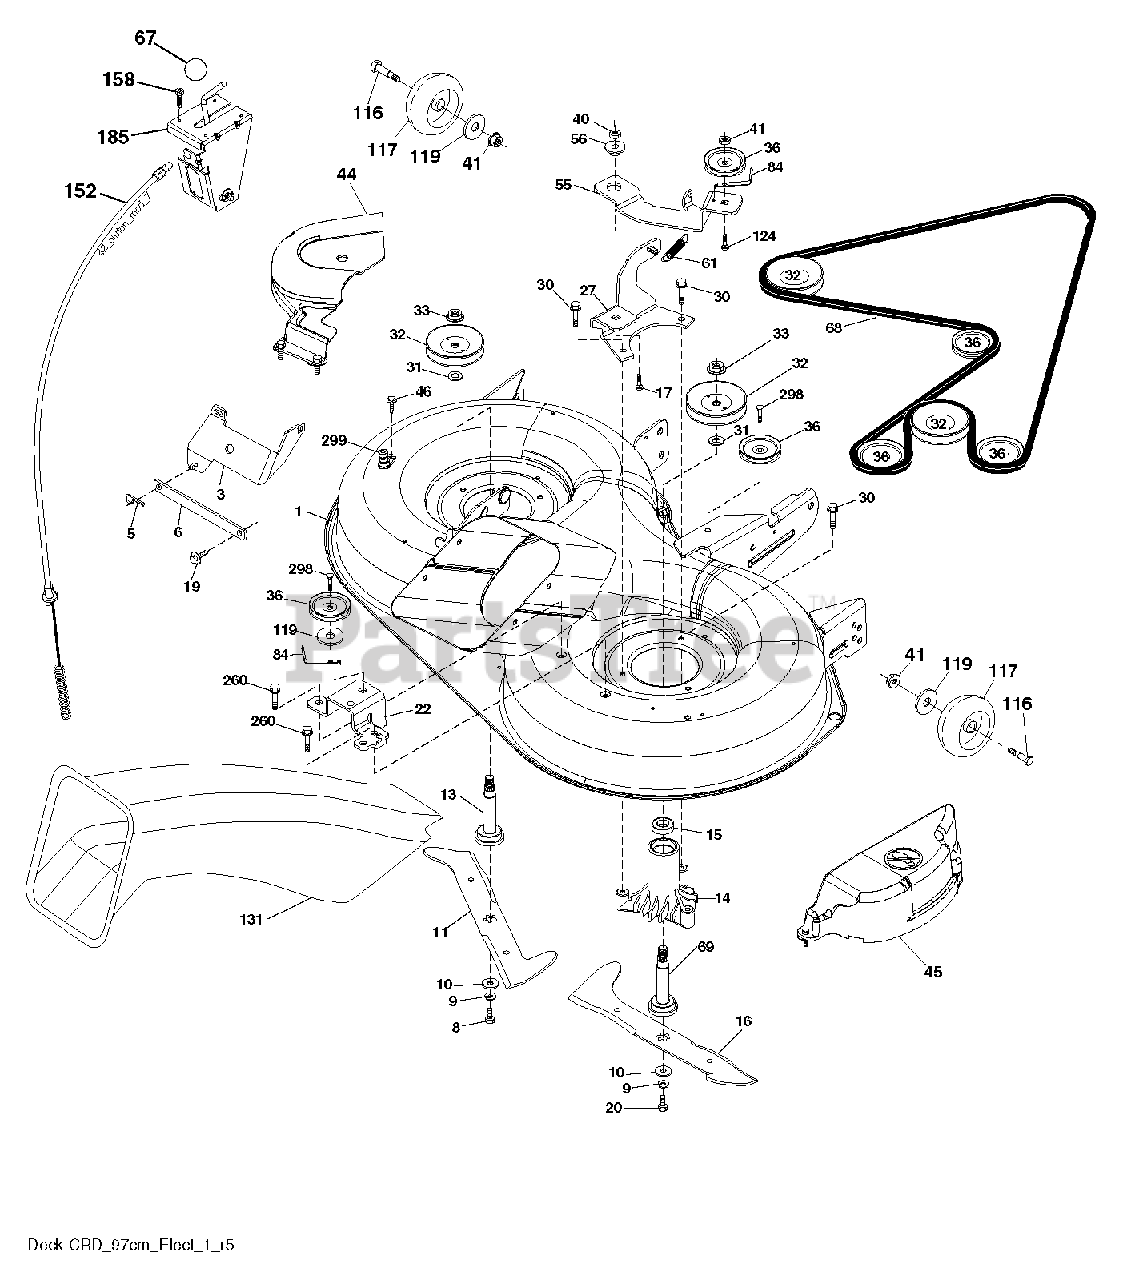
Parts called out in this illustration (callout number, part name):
3	BRACKET.ASM.BAR.SWAY.CHASS
5	RETAINER-SPRNG RB
6	BAR SWAY
9	LOCKWASHER
10	WASHER.BLADE
11	BLADE.3N1.LH.CRD.97
13	SHAFT ASM VENT
14	HSG MANDREL
16	BLADE.3N1.RH.CRD.97
17	BOLT.3/8-14X1.25
19	BOLT SHD 5/16-18
22	BRACKET.SUPT.IDLER.REAR.RH
27	BRACKET.ASM.SUSP.REAR.RH.
30	SCREW, WASHER HEAD
31	WASHER.SPACER.MANDREL
32	PULLEY MANDREL
33	NUT.FLANGE.LOCK.TOP
36	PULLEY.IDLER.4.25
40	LOCKNUT
41	NUT LOCK FLG 3/8-16 UNC
46	SCREW.1/4-20X5/8
56	SPACER.RETAINER.MOWER
67	KNOB T (3/8 HOLE)
68	BELT.DRIVE.CRD.97.2010
69	SHAFT.ASM.W/LWR.BRG.RH.THREAD
84	KEEPER, BELT IDLER
116	BOLT.SHOULDER.3/8-16X3-5/8
117	WHEEL. GUAGE RALLY
124	BOLT.3/8-16X1.50
131	CHUTE BAGGER
158	SCREW
185	HEAD ASM. CABLE CLUTCH
260	SCREW 3/8-16X1/2
298	SCREW LT
299	PORT.WASHOUT
